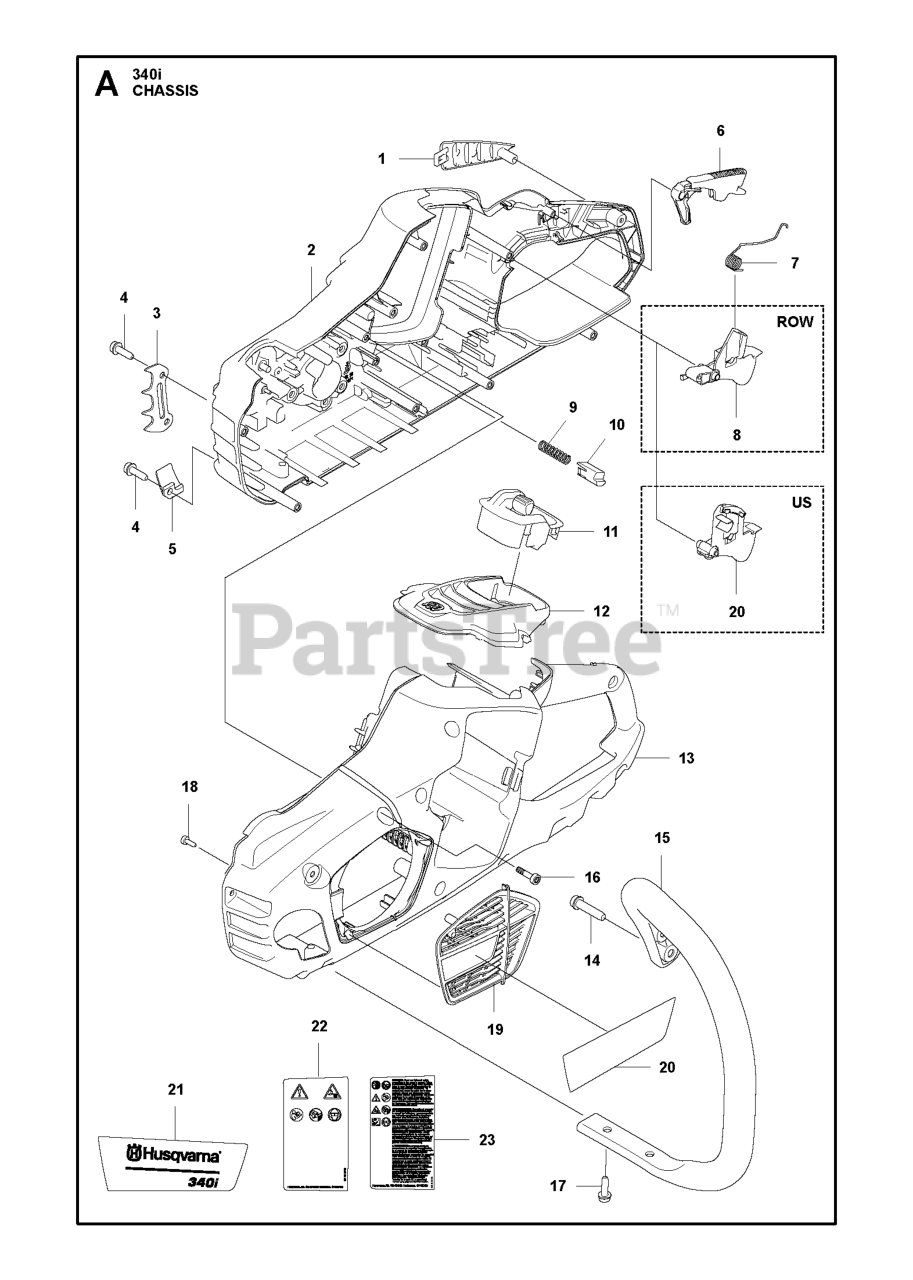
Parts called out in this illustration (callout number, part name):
3	INDRE BARKSTØD
5	CHAIN CATCHER
8	Throttles
9	SPRING PUSH OUT
10	PUSH BUTTON
16	SCREW ITXSCT PW4.2X18 10.9 ZN
17	SCREW ITXSCFT PL6X16 T27 10.9
